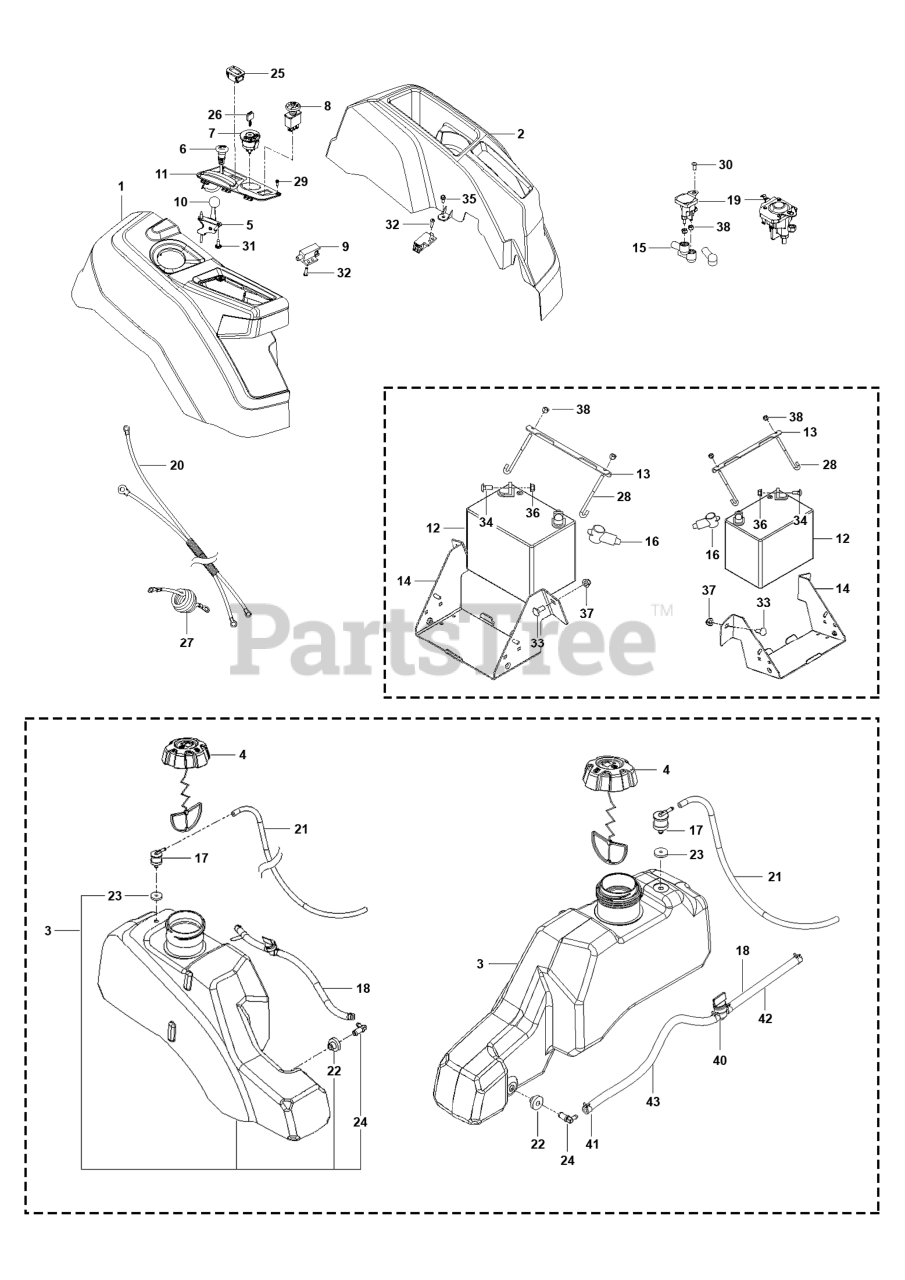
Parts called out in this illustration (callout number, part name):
1	CONSOLE.ASSY.RZ.REFRESH.RH
2	CONSOLE.LH.ASM
3	TANK.ASM3"NECK.NOCAP.NOSHDRZ18
4	FUEL CAP
4	CAP ASSY FUEL 3" GRAY
5	THROTTLE CABLE
5	CABLE.THROTTLE.37"
5	THROTTLE CONTROL W/BALL KNOB
6	CHOKE.PUSH-IN.STYLE.57"
6	CHOKE.PUSH-IN.STYLE
7	RP IGNITION SWITCH
8	RP SWITCH.PTO.TERMINAL.STD.RED
9	SWITCH.INTLK.RZ.RFRSH.BUTTON
10	KNOB.ROUND.BALL.BLACK
11	CONTROL.PANEL.RZ.REFRESH.RH
12	BATTERY, 12 V 300 AMP DRY
13	BRACKET.PNT.MOUNT.BATTERY.EDIP
14	BOX.PNT.BATTERY.RZ.EDIP
15	TERMINAL COVER
17	VALVE.FUEL.CHECK
18	FUEL.HOSE.SHUT.OFF.ASM.10".3"
18	FUEL.HOSE.SHUT.OFF.ASM.10".18"
19	SOLENOID.STARTER.BRASS.PLUNGER
20	HARNESS.BTTRY.CABLE.RZ.REFRESH
21	HOSE 3/16" VAPOR LINE 29" LENG
21	HOSE.3/16".VAPOR.LINE.50"LGTH
21	HOSE.3/16".VAPOR.LINE.18"LGTH
22	BUSHING OUTLET T
23	GROMMET.ROV.SENTEC
24	STEM FUEL TANK
25	GUAGE.SRVCMNDR.HRMTR.
26	KEY.CHAIN.BLISTER.PACK.GEN.USA
26	KEY MLD GEN DELTA
27	CABLE BATTERY POS RZ
28	HOOK.J.BATTERY
29	SCREW 6-19X.437
30	SCR 1/4-20 X 5/8 BTN SKT HD ZD
31	SCREW.PAN.HEAD.#10
32	SCR #10-24 X .75 SKT HD BLK
33	RHSNB 3/8C X 1
34	BOLT 5/16C X 3/4" CARRIAGE
35	HCS 1/4-20.
35	SCREW.PAN.HEAD.#10
36	5/16-18 NYLOC FLANGE NUT
37	NUT 3/8-16 HEX FLG NYLOC ZD
38	NUT.1/4-20.HEX.NYLOC.ZD
40	FUEL VALVE
41	HOSE CLAMP
42	HOSE.1/4".LOW.PERM.FUEL.LN.10"
43	HOSE 1/4" LOW PERMEATION FUEL
43	HOSE.1/4".LOW.PERM.FUEL.LN.3"
